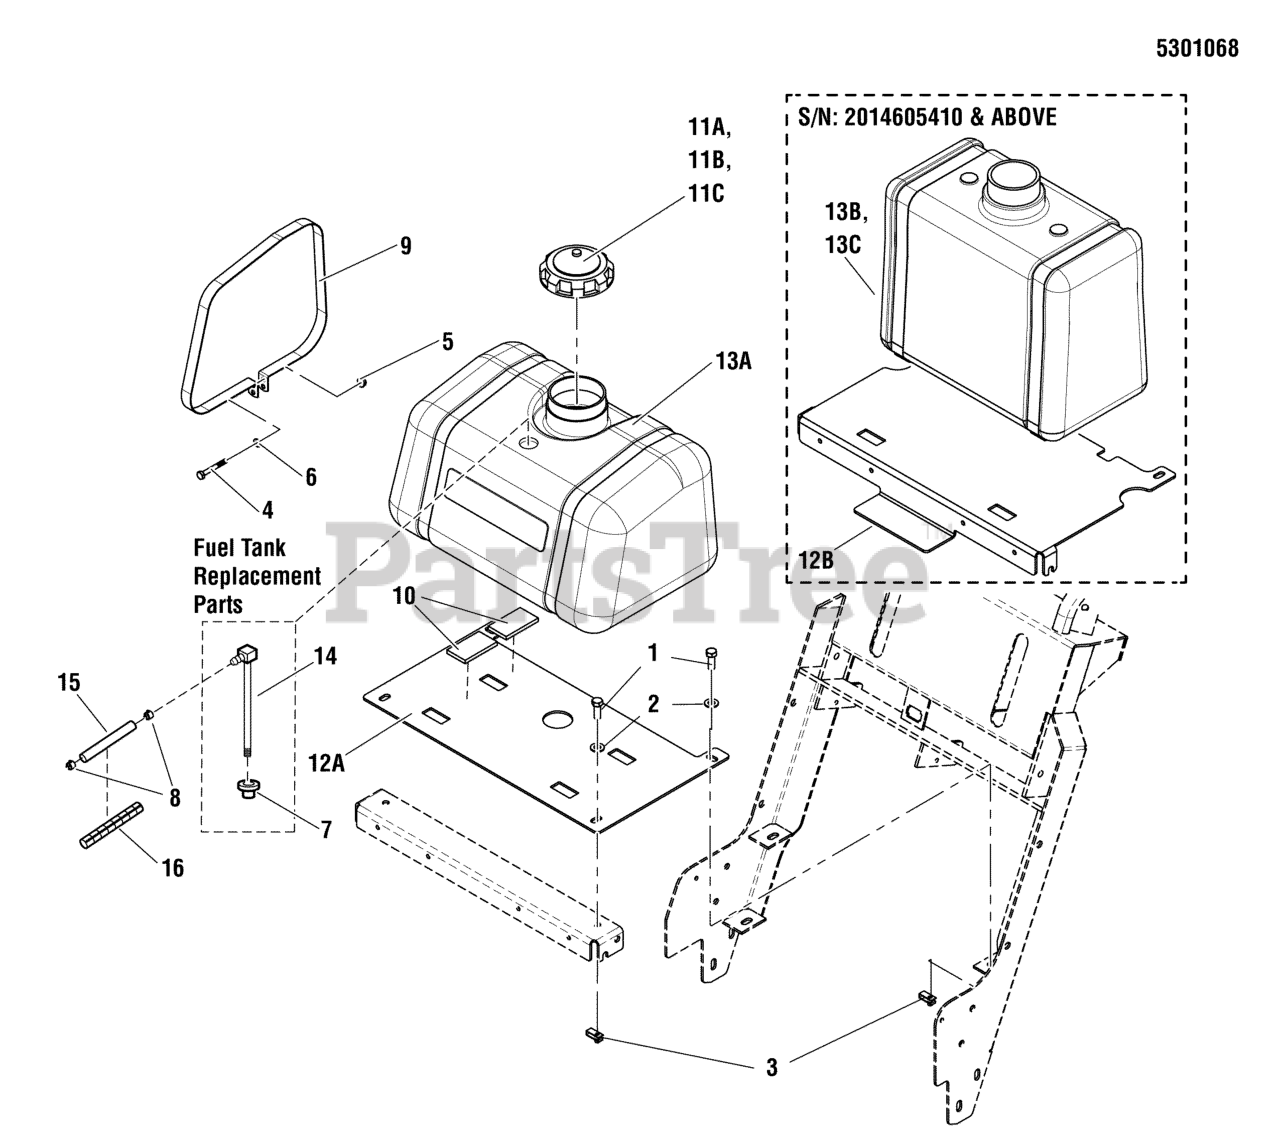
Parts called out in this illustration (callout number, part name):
1	BOLT, 3/8-16 X 1" GD5 CZ
2	WASHER, 3/8 SAE
3	BODY CLIP, 3/8-16 X .688" DEEP
4	BOLT, 1/4-20 X 1-3/4", GD5
5	NUT, 1/4-20 HEX NYLOCK FLANGE
6	WASHER, 1/4 SAE
7	BUSHING-FUEL TANK RED RUBBER
8	CLAMP, HOSE, EXTERNAL, 1/2 - RED
9	STRAP, FUEL TANK
10	PAD, RUBBER MOUNT, 1/4 MAT
14	PICKUP TUBE ASM, FUEL TANK, 8.0" (SV)
15	HOSE, 1/4" FUEL, 13.00"
16	WIRE LOOM, 1/2" ID, 17" LONG
18	GROMMET
